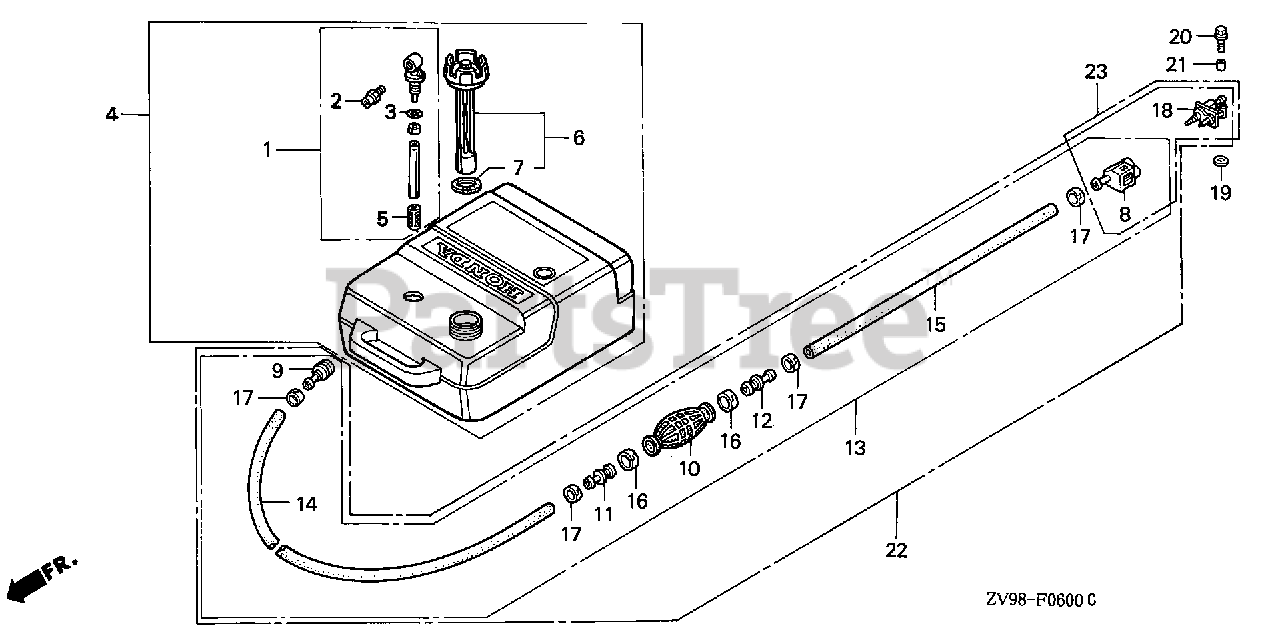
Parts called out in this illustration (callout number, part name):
1	JOINT ASSY., FUEL
2	FITTING, QUICK DISCONNECT
3	O-RING
4	TANK ASSY., FUEL
5	FILTER, FUEL
6	CAP, FUEL FILLER
7	GASKET, FUEL CAP
8	CONNECTOR ASSY., FUEL (A)
9	CONNECTOR, FUEL
10	BULB, PRIMER
11	VALVE, IN.
12	VALVE, OUTLET
13	TUBE ASSY., FUEL
14	TUBE, FUEL LONG (7.3X2000)
15	TUBE, FUEL SHORT (6.3X500)
16	BAND, TUBE CLIP (20MM)
17	BAND, TUBE CLIP (12.5MM)
18	CONNECTOR ASSY., FUEL (B)
19	WASHER, PIVOT
20	BOLT, FLANGE (6X20)
21	COLLAR, DISTANCE (6MM)
22	CONNECTOR SET, FUEL TUBE
23	CONNECTOR SET, FUEL
